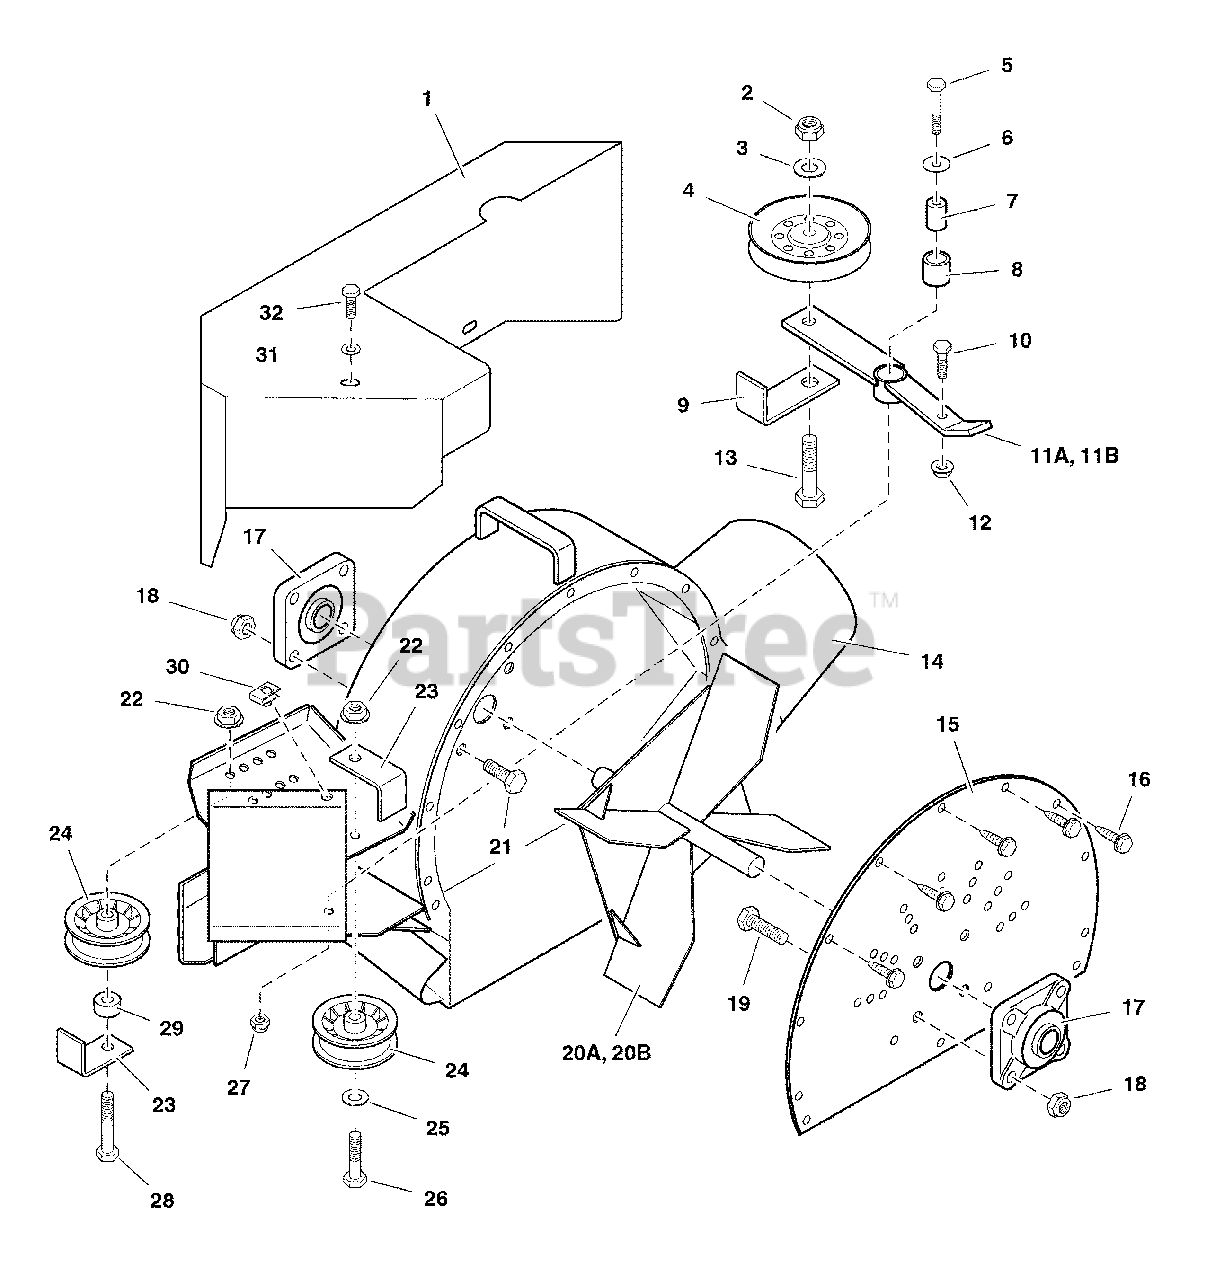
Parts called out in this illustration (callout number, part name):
1	BELT GUARD
2	NUT, 1/2-13 Hex Nylon Lock
3	WASHER, 1/2 SAE
4	PULLEY, V-Idler
5	BOLT, 5/16-18 x 1-3/4
6	WASHER, 5/16" Fender
7	SPACER, .32 x .75 x 1.06
8	BUSHING, Brass
10	BOLT, 5/16-18 x 1-1/4
12	NUT, 5/16-18 Hex Small Serrated Flange
13	BOLT, 1/2-13 x 2-1/4
14	BLOWER HOUSING
15	BACK PLATE
16	BOLT, Self-Tapping, 5/16-18 x 3/4
17	BEARING
18	NUT, 7/16-14 Hex Nylon Lock
19	BOLT, 7/16-14 x 1-1/2
21	BOLT, 7/16-14 x 1-1/4
22	NUT, 3/8-16 Hex Serrated Flange
24	PULLEY, IDLER, 2.75 DIA X .376 ID
25	WASHER, 3/8 SAE
26	BOLT, 3/8-16 x 1-3/4
27	NUT, 5/16-18 Hex Nylon Lock
28	BOLT, 3/8-16 x 2-1/4
29	SPACER, .39 x 1.00 x .50
30	BODY CLIP, 5/16-18
31	WASHER, 5/16" SAE
32	BOLT, 5/16-18 X 1 GD5 YZ
